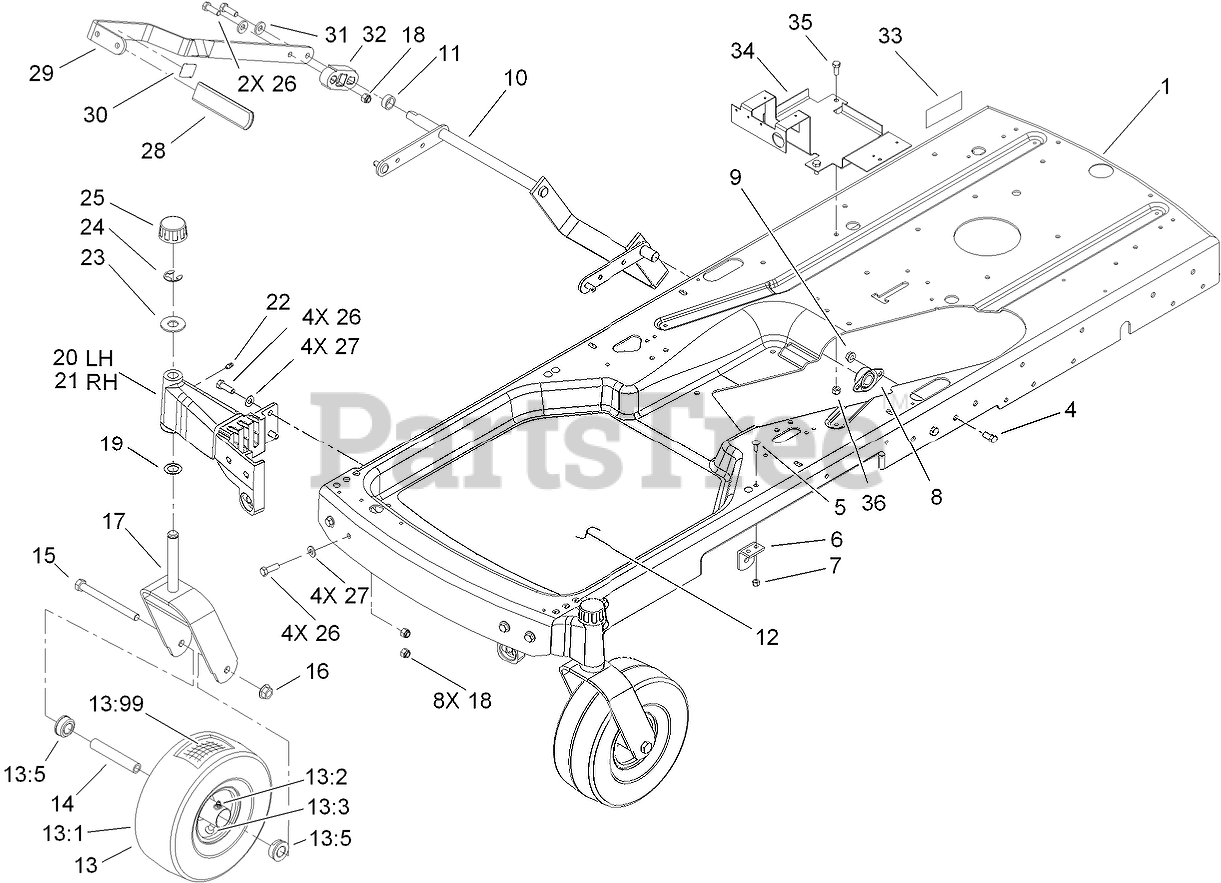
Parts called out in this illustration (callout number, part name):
4	SCREW-HH
5	BOLT-CARR
6	BRACKET-LIFT
7	NUT-LOCK, NI
8	BEARING-FLANGE, SIDE
9	NUT-HHF, WHIZ
10	LIFT ARM ASM
11	SPACER
12	PAD-ANTISKID
13	FRONT WHEEL AND TIRE ASM
13:2	FITTING-GREASE
13:3	STEM-VALVE
13:5	BUSHING-FLANGE
13:99	TUBE-INNER (W/VALVE)
14	BUSHING-SPANNER
15	SCREW-HH
16	NUT-HF
17	CASTER FORK ASM
18	NUT-LOCK, NI
19	WASHER-THRUST
21	CASTER-RH
22	FITTING-GREASE
23	WASHER-PLAIN
24	RING-RETAINING, EXT
25	CAP-HUB
26	SCREW-HH
27	WASHER-FLAT
28	GRIP-LEVER, LIFT
29	LEVER-LIFT
30	DECAL-HOC
31	WASHER-BELLEVILLE
32	BLOCK-LIFT
33	DECAL-TRANSPORT
34	HOLDER-BATTERY
35	SCREW-HH
36	NUT-LOCK, NI
